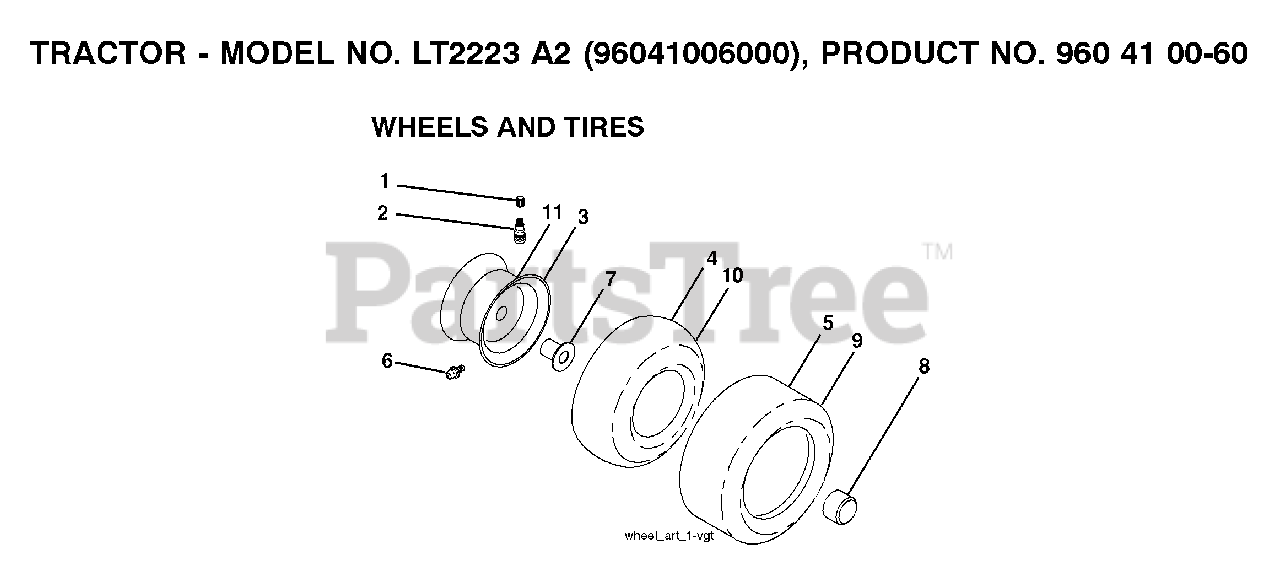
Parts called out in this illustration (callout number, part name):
1	VALVE CAP
2	VALVE STEM LT
3	RIM ASM 6" FRONT SILVER
4	TUBE.5.3/4.5/6
5	TIRE HEAVY DUTY
6	FITTING LT
7	BEARING T
8	CAP, AXLE BLK
9	TIRE.TS.20X10-8
10	TUBE
11	RIM ASM 8" REAR SILVER
